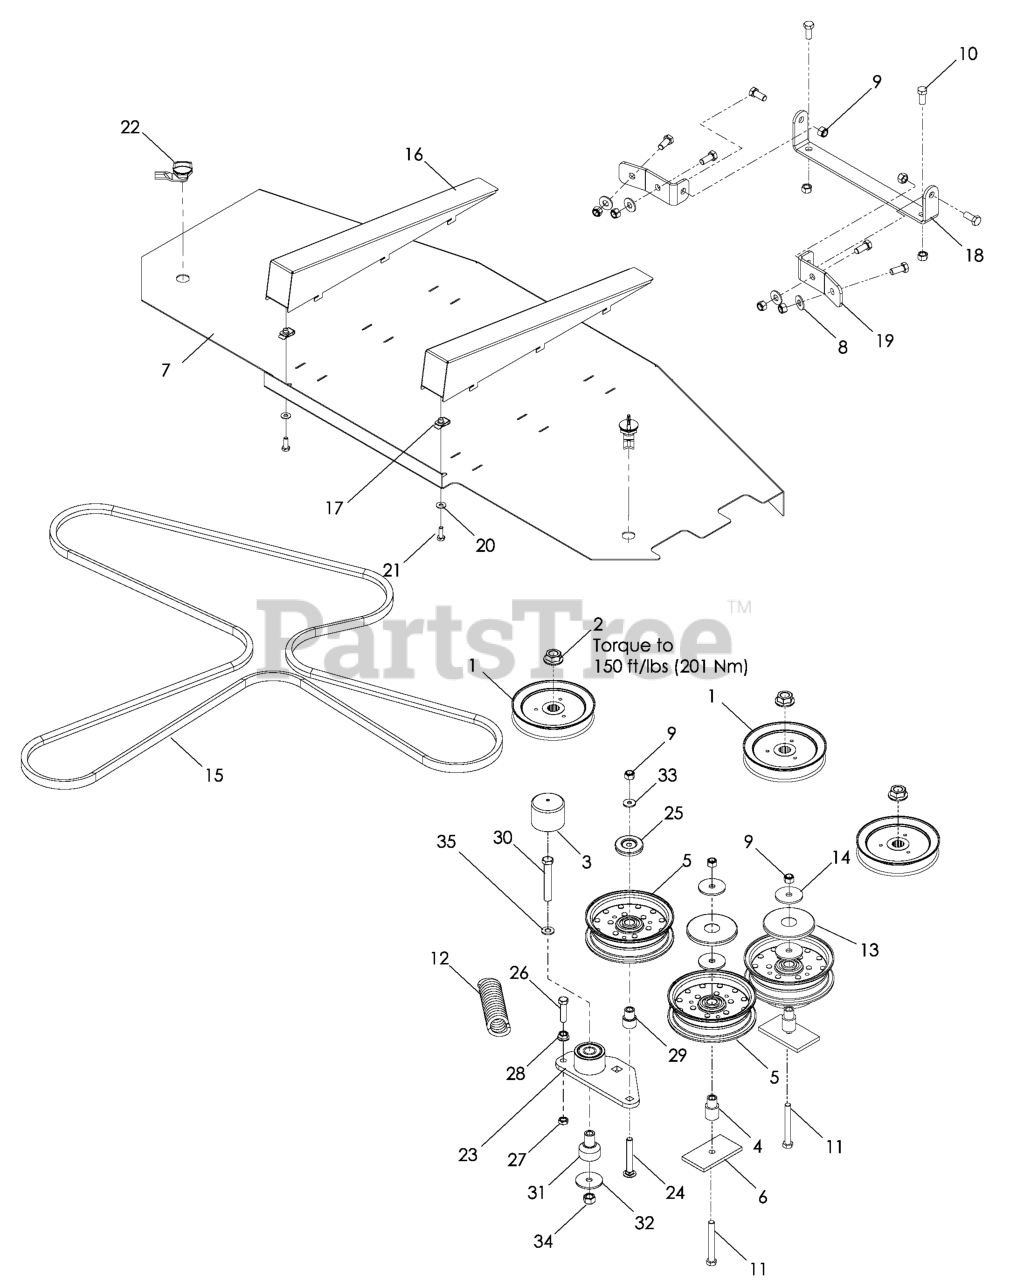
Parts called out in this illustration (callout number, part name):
1	PULLEY - 5.25
2	NUT FLANGE 3/4-16
3	CAP, VINYL
4	IDLER BUSHING
5	IDLER PULLEY
6	SUPPORT PLATE
7	COVER - BELT, 48 PAINTED
8	WASHER 3/8 FLAT
9	NUT 3/8-16 NYLOC
10	HCS 3/8-16 X 7/8 GR 5 ZD
11	HCS 3/8C X 3
13	TOP DUST CAP
14	WASHER, 3/8 SPEC
16	WEDGE - PAINTED
17	1/4C - U TYPE RETAINER
18	HINGE, BIN
19	BASE HINGE - PAINTED
20	WASHER 1/4 SAE
21	HCS 1/4C X 3/4 HCS
22	LATCH, SHORT WING
23	ARM-IDLER W/BRG
24	RHSNB 3/8-16 X 2.75
25	DUST SHIELD
26	HCS 3/8-16 X 1-1/2
27	NUT 3/8-16 HEX JAM
28	NUT 3/8C WHIZ
29	BUSHING, IDLER
30	HCS 1/2C X 3 1/4
31	PIVOT, BEARING
32	WASHER, SUPPORT
33	WASHER, 3/8 THICK
34	NUT 1/2-13 HEX NYLOC ZD
35	CONTACT BELLSPR 1/2
